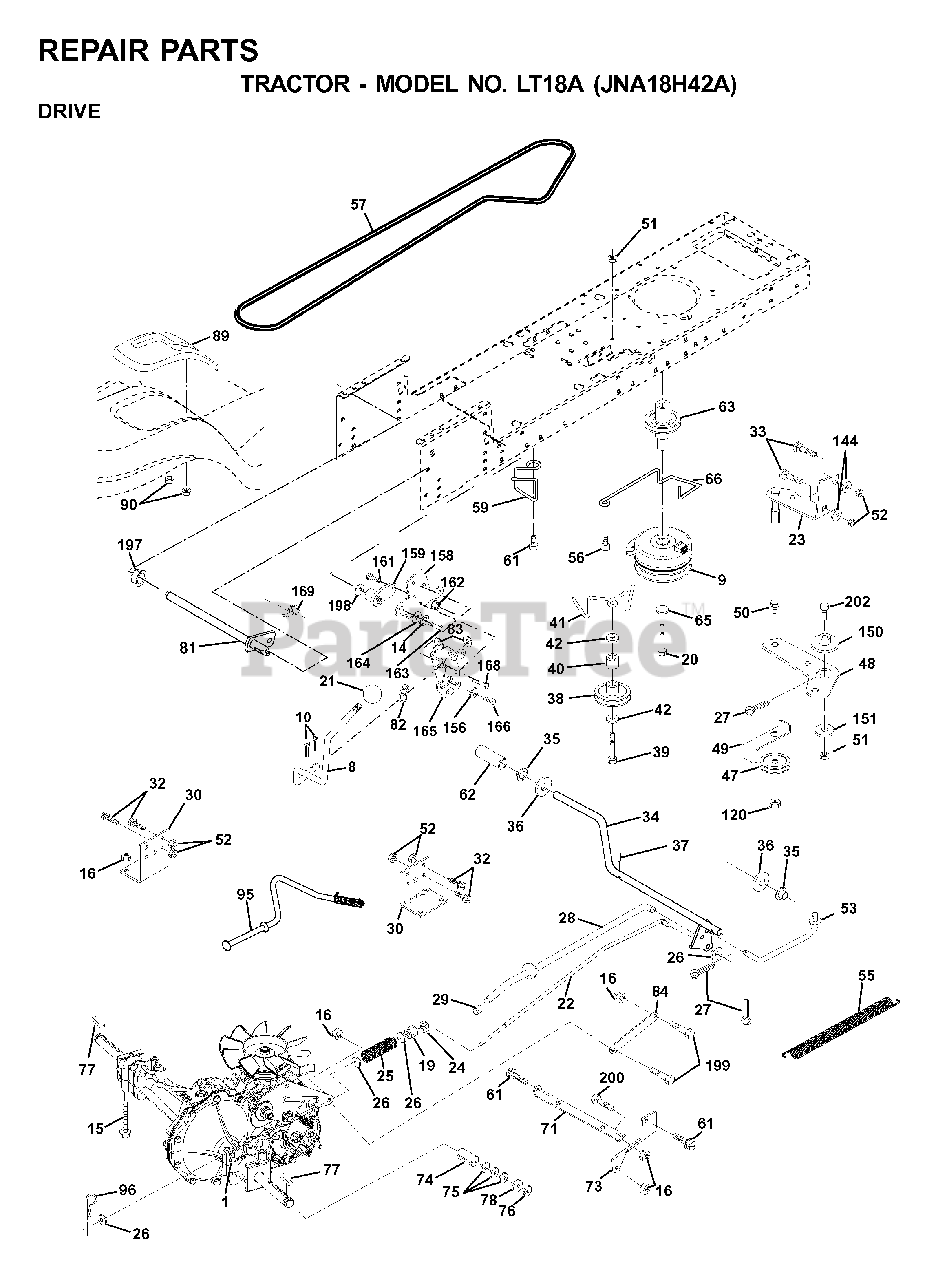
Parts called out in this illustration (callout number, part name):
8	ROD SHIFT FENDER ADJUST STLT
9	ELECTRIC CLUTCH
10	PIN COTTER
14	LOCKWASHER
15	BOLT HEX 5/16-18 GR 5
16	NUT.71038.31-18.HEX.NYLOCK
19	NUT
20	BOLT HEX
21	KNOB.DELUXE.(PISTOL.GRIP).BLAC
22	ROD BRAKE HYDRO
24	NUT
25	SPRING ROD LT
27	COTTER PIN
28	ROD, PARKING BRAKE
29	PLUNGER CAP
30	BRKT, TRNSXLE MNT 20"
32	BOLT
33	BOLT
34	SHAFT, FOOT PEDAL
35	BEARING.NYLON
36	WASHER LT
37	DRIVE PIN
38	PULLEY.FLAT
39	BOLT
40	SPACER, SPLIT
41	KEEPER, BELT IDLER
42	WASHER
47	IDLER PULLEY
48	BELLCRANK, CLUTCH
49	RETAIN BELT
50	BOLT
51	LOCKNUT
52	LOCKNUT
53	LINK, CLUTCH LT
55	SPRING, RETURN LT
57	DRIVE BELT, LTH & YTH TRACTORS
59	KEEPER, BELT CENTER
61	SCREW 3/8-16X3/4
62	PEDAL COVER T
63	PULLEY, ENGINE
65	LOCKWASHER
66	KEEPER BELT ENGINE
71	STRAP TORQUE LH HYDRO
73	STRAP TORQUE RH HYDRO
74	SPACER AXLE
76	E-RING LT
77	SQUARE KEY
81	SHAFT ASM CROSS TAPERED
82	SPRING,TORSION
83	WASHER
84	LINK TRANSAXLE
95	CONTROL ASM. BYPASS HYDRO
96	RETAINER M
120	NUT LOCK FLG 3/8-16 UNC
144	WASHER
150	SPACER, RETAINER
151	WASHER 12/32X2X10GA
156	WASHER.SRRTD.5/16
158	BRACKET
159	HUB
161	BOLT
162	NUT.CROWNLOCK.1/4
165	RP BRACKET
168	BOLT.SHOULDER.5/16-18X
169	PLATE.FASTENING.CROSS.SHAFT
197	NYLINER SNAP 5/8" ID
198	WASHER.NYL.7/8IDX.105"HYD CR
199	BOLT SHOULDER 5/16-18 UNC
200	BOLT
202	BOLT.3/8-16X1.50
